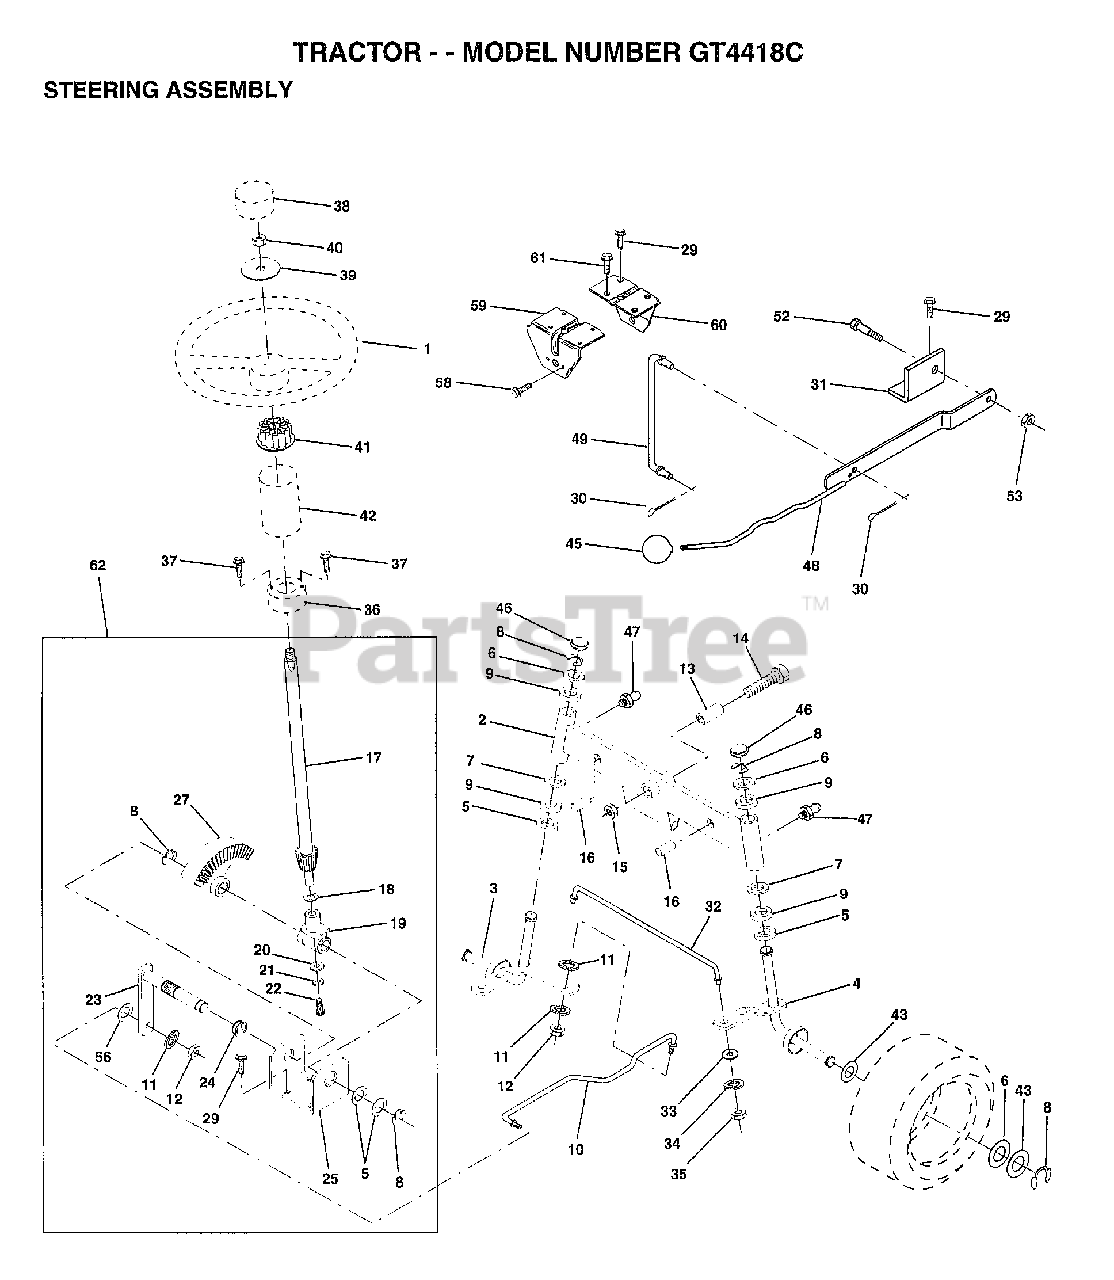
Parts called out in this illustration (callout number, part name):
2	AXLE ASM FRONT
5	WASHER .T
6	WASHER
7	WASHER
8	RING
9	COL. SRTG. BEAR.
11	LOCKWASHER
13	BEARING
14	BOLT LT
15	"NUT-LOC,FLANGE LT"
16	AXLE PIN
17	STEERING SHAFT
18	THRUST WASHER
19	SUPPORT.SHAFT
21	LOCKWASHER
22	"SCREW,SPECIAL"
24	NYLINER T
25	"BRKT,STEERING"
27	GEAR SECTOR
29	SCREW
30	COTTER PIN
31	BRKT.PVT.MAN.LVR.
32	ROD.TIE.19.75
33	WASHER M
34	LOCKWASHER
35	NUT.LOCK.5/16-24
36	BUSHING.STRG.3/4
37	SCREW.10-24X1/2
38	ST WHL INSERT CAP
39	WASHER
41	ADAPTER LT
42	BOOT SHAFT STEER
43	WASHER
45	KNOB T (1/2-HOLE)
46	CAP
47	ZERK M
48	LEVER.CLUTCH.MOWR
49	LINK CLTCH W/NUTS
52	"BOLT, SHOULDER LT"
56	WASHER
58	SCREW LT
59	SUPPORT-SADDL T
60	SUPPORT.SADDLE.FT
61	SCREW SPECIAL
